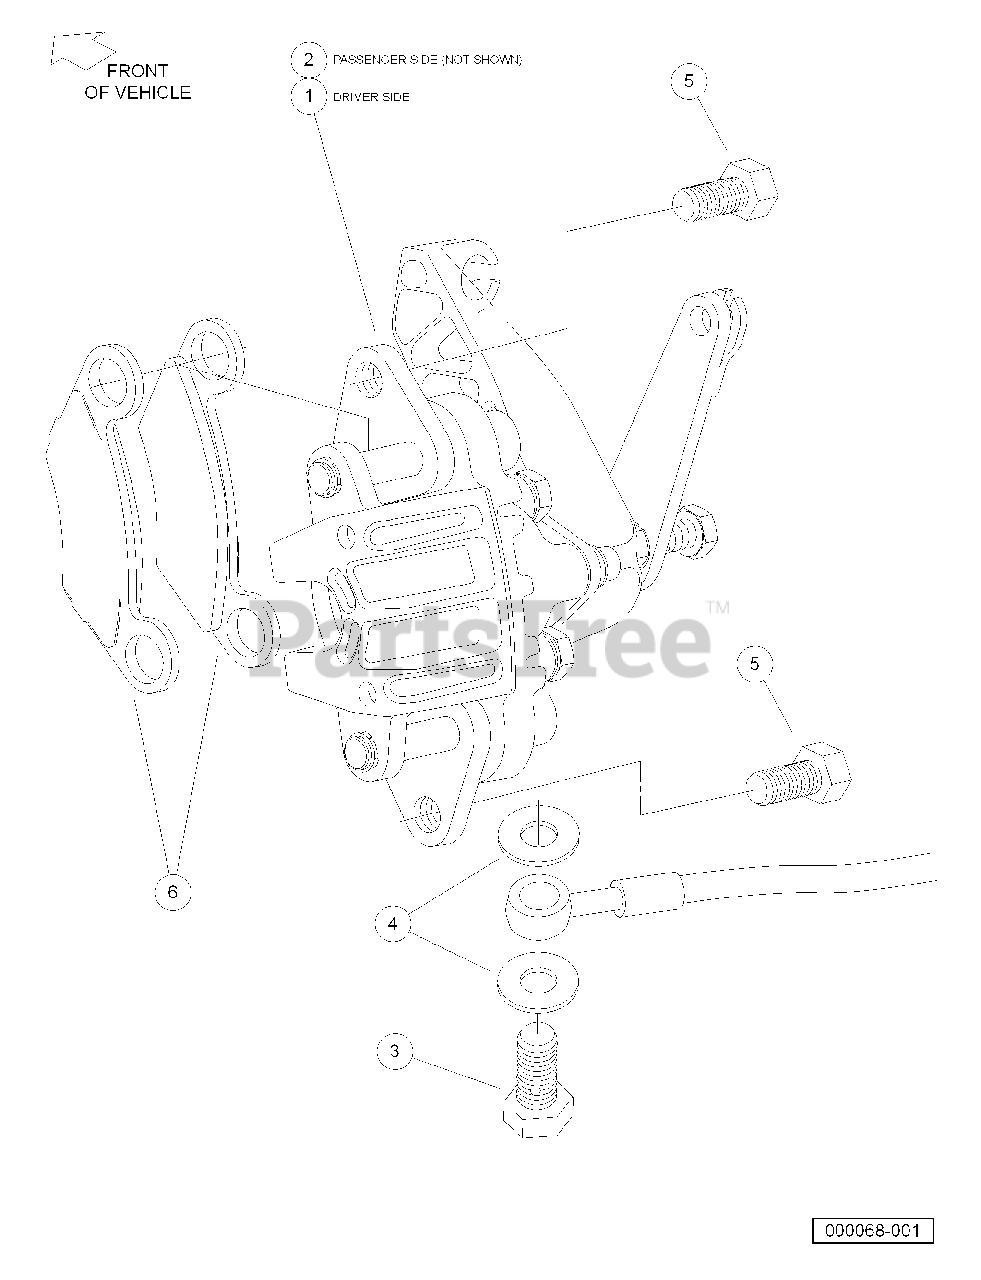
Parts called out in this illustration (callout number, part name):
1	Caliper, Brake, Hydro-Mechanical, LH
2	Caliper, Brake, Hydro-Mechanical, RH
3	Bolt, Banjo, M10x1x19
4	Washer, Copper, M10 Crush
5	Bolt Flange Head, 3/8-24x.750 with Loctite
6	Service Kit, Brake Pad
